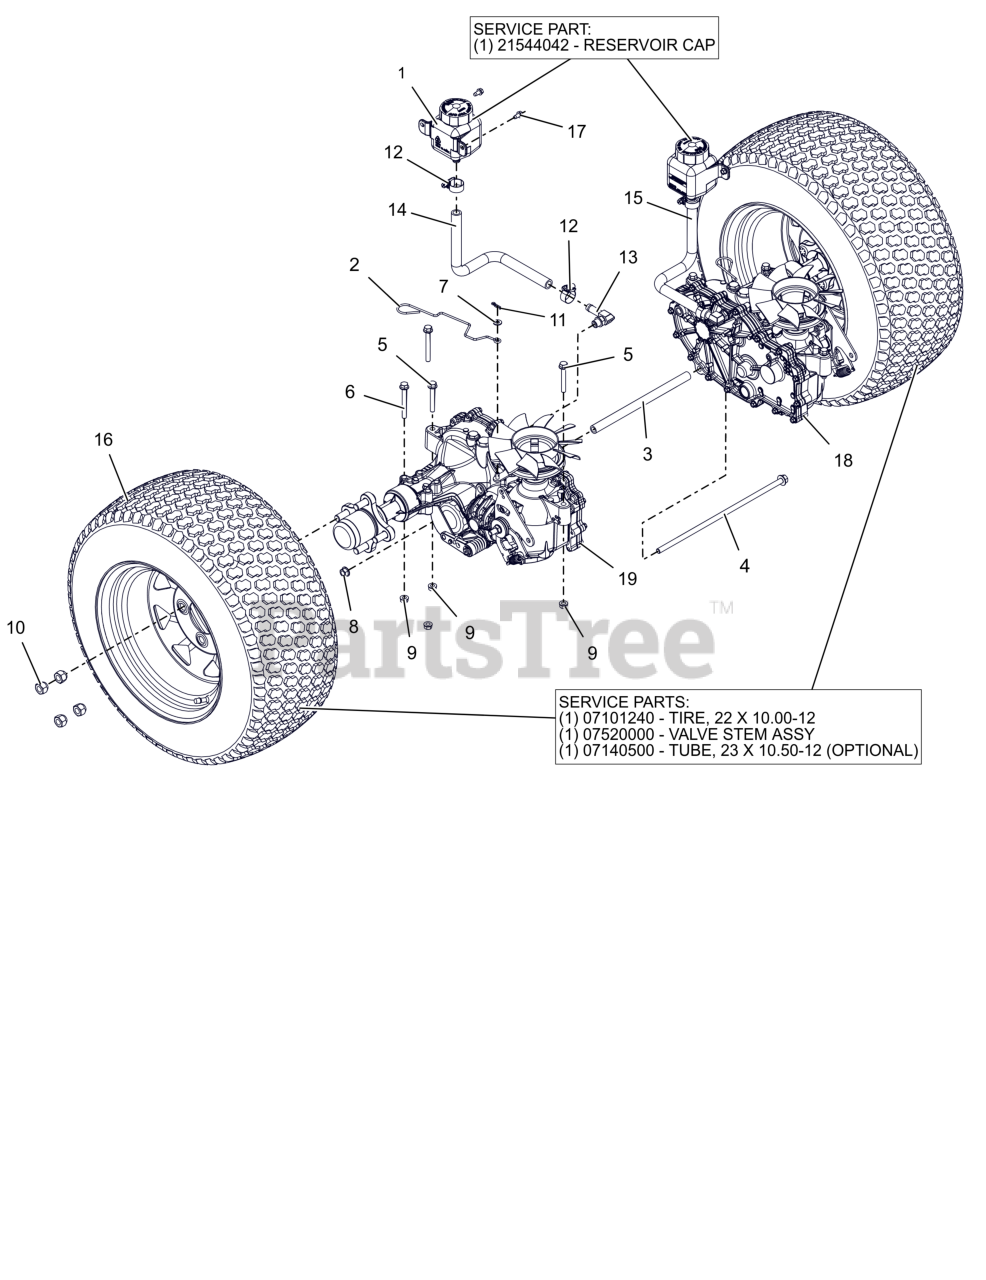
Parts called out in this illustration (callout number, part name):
1	TANK, EXPANSION
1	CAP, HYDRO RESERVOIR REPLAC.
2	WIREFORM, DUMP VALVE
3	SPCR,TRANS. .406IDX.63ODX9.95L
4	BLT,HEX-FLG .38-16X13 G5 ZCC
5	BLT,HEX-FLG .31-18X2.25 G5 ZCC
6	BLT,HEX-FLG .31-18X2.75 G5 ZCC
7	WSHR,FLT .281X.625X.065 ZCC
8	NUT-LK-TOP-FLG .38-16 ZC120
9	NUT,LK-CTR-FLG .31-18 GF ZCC
10	NUT, WHEEL .50-20 ZCC
11	PIN, HAIR #225 .072X1.09
12	CLAMP,.88 DIA. HOSE
13	FITTING, HYD (90 DEG)
14	HOSE, FORMED EXPANSION -HD RH
15	HOSE, FORMED EXPANSION -HD LH
16	ASM-WHL/TIRE 22X10-12 LG BLK
16	TIRE, 22X10.00-12
16	VALVE STEM ASS'Y
16	TIRE TUBE 22,23,24/8.50/9.50/10.00/10.50/12.00-12 4 PLY TR13 STRAIGHT VALVE
17	SCR-TAP .25-20X.50 HWH ZCC
18	TRANSAXLE, ZT3100 - LH
19	TRANSAXLE, ZT3100 - RH
